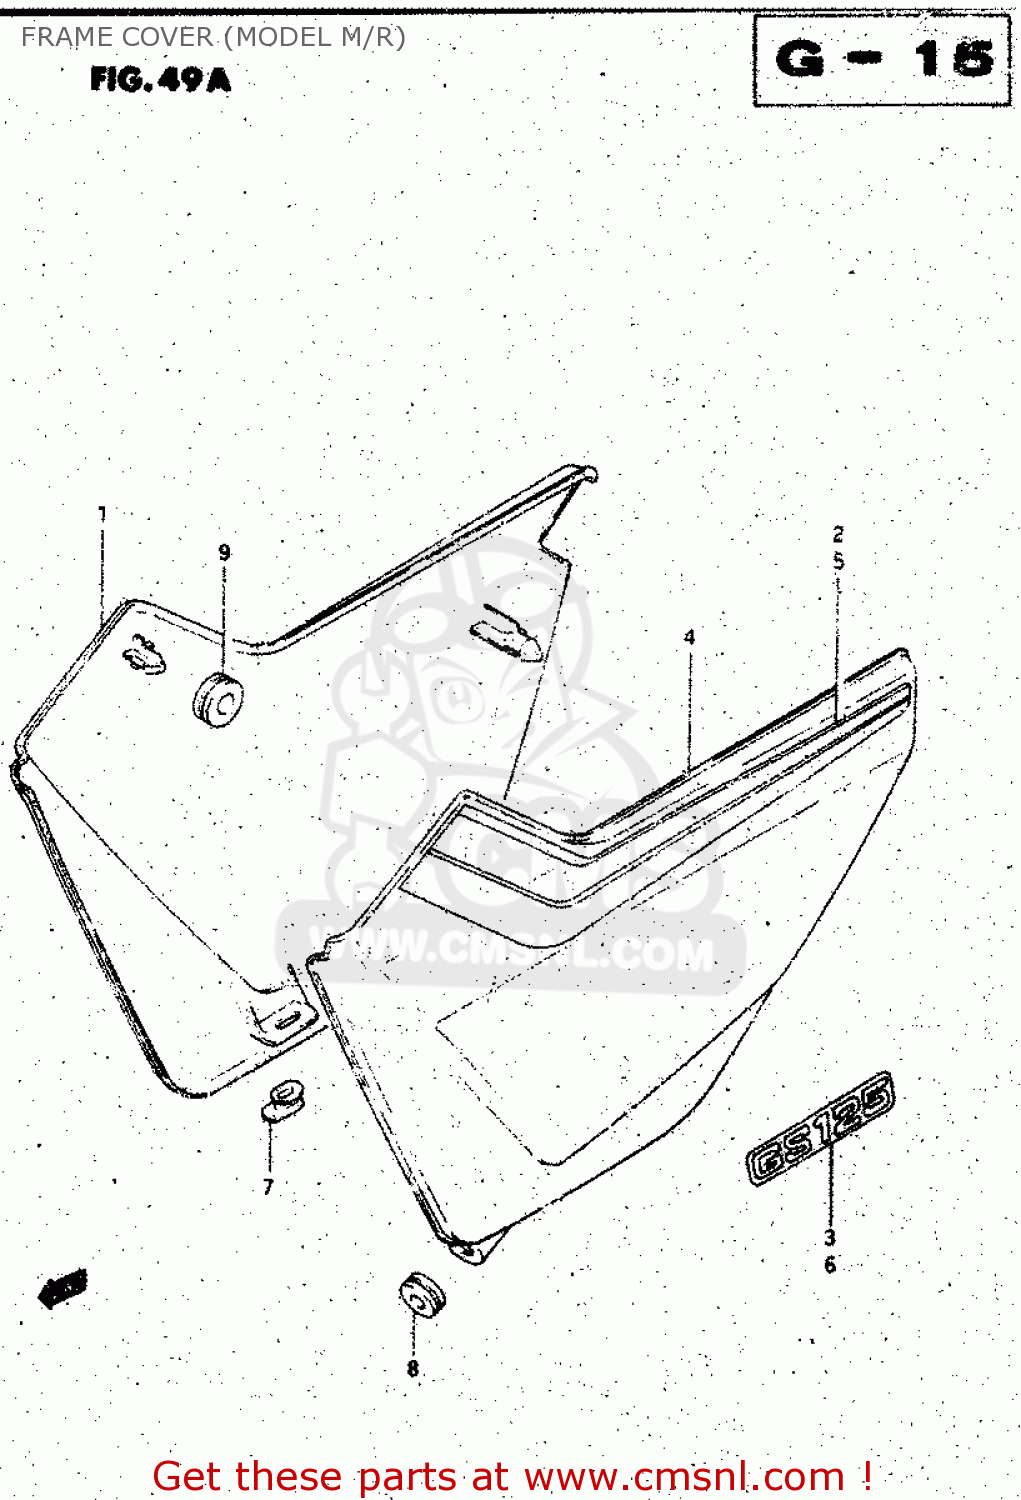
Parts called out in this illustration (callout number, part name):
1	COVER,FRAME,R(RED)
2	TAPE SET, FRAME COVER RH
3	EMBLEM (WHITE)
4	COVER,FRAME,L(RED)
5	TAPE SET, FRAME COVER LH
6	EMBLEM (WHITE)
7	CUSHION
8	CUSHION
9	CUSHION
